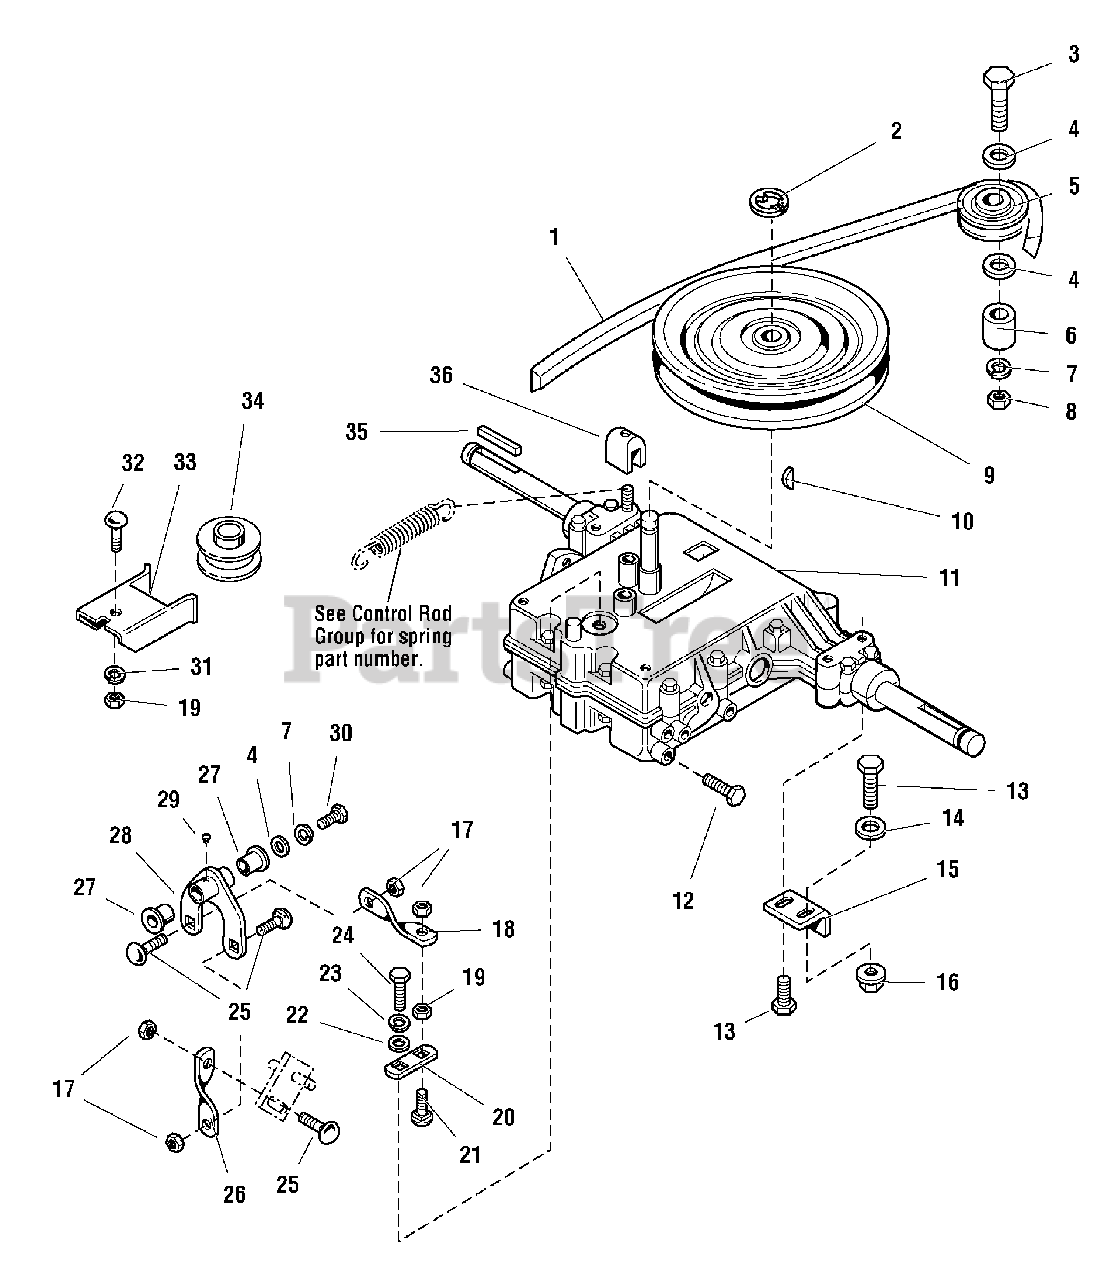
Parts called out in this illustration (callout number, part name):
1	V-BELT, 93-7/64"
2	RING, Retaining
3	CAPSCREW, Hex Hd., 3/8-16 x 2
4	WASHER, Plain, 3/8
5	PULLEY, Idler, V
7	LOCKWASHER, 3/8
8	NUT, Hex, Full, 3/8-16
9	PULLEY ASSY.
10	KEY, Woodruff #9
12	SCREW, Taptite, 5/16-18 x 5/8
13	SCREW, Taptite, 5/16-18 x 2-1/2
14	WASHER
15	ANCHOR, Torsion Bar
16	NUT, Hex, Flange Whiz, 5/16-18
17	NUT, Hex, Nylon Lock, 5/16-18
18	LINK, Shift, Lower
19	NUT, Hex, Full, 5/16-18
20	LEVER, Shift
21	CARRIAGE BOLT, 5/16-18 x 1-1/2
22	WASHER, Plain
23	LOCKWASHER, 1/4
24	CAPSCREW, Hex, 1/4-28 x 5/8
25	CARRIAGE BOLT, 5/16-18 x 1-1/4
26	LINK, Shift, Upper
27	BUSHING, Plastic, 5/8
28	BELLCRANK ASSY.
29	GREASE FITTING
30	CAPSCREW, Hex Hd., 3/8-16 x 3/4
31	LOCKWASHER, 5/16
32	GUARD, Belt
33	CARRIAGE BOLT, 5/16-18 x 3/4
34	PULLEY, Half
35	KEY
36	CLIP, Tinnerman
